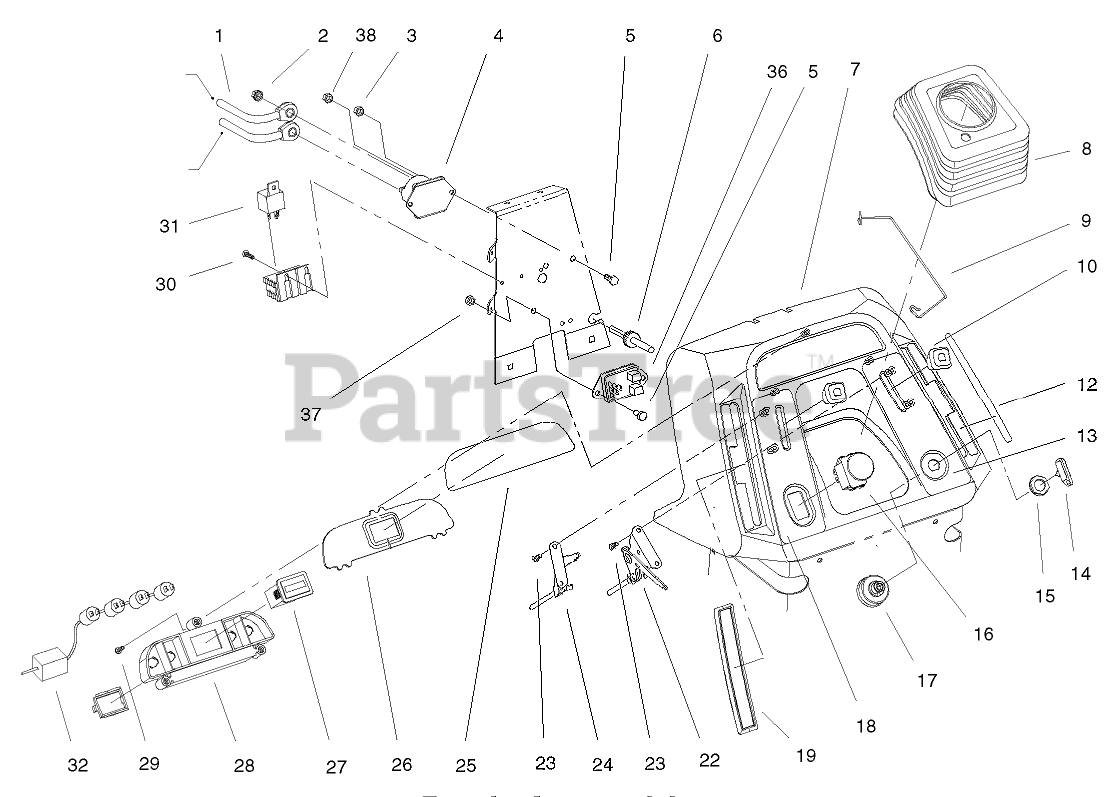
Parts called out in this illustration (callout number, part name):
1	CABLE-BATTERY, RED
2	NUT-KEPS
3	NUT-LOCK, NI
4	SOLENOID
5	SCREW-HH
6	GROMMET-RUBBER
8	BOOT-STEERING
9	CLIP-BOOT
12	DECAL - SHIFT
13	DECAL-THROTTLE, IGNITION
14	KEY-IGNITION
16	SWITCH-PTO
17	SWITCH-IGNITION
18	DECAL-PTO / CHOKE
19	COVER-SLOT, LH
22	CONTROL - THROTTLE
24	CONTROL-CHOKE
25	DECAL-LENS, DASH
26	LENS-DASH
27	HOURMETER
28	HOUSING-LIGHT, INDICATOR
29	SCREW
30	SCREW-PPHTF
31	RELAY
32	HARNESS-LAMP
36	MODULE-CLUTCH
37	NUT-LOCK, NI
38	NUT-KEPS
